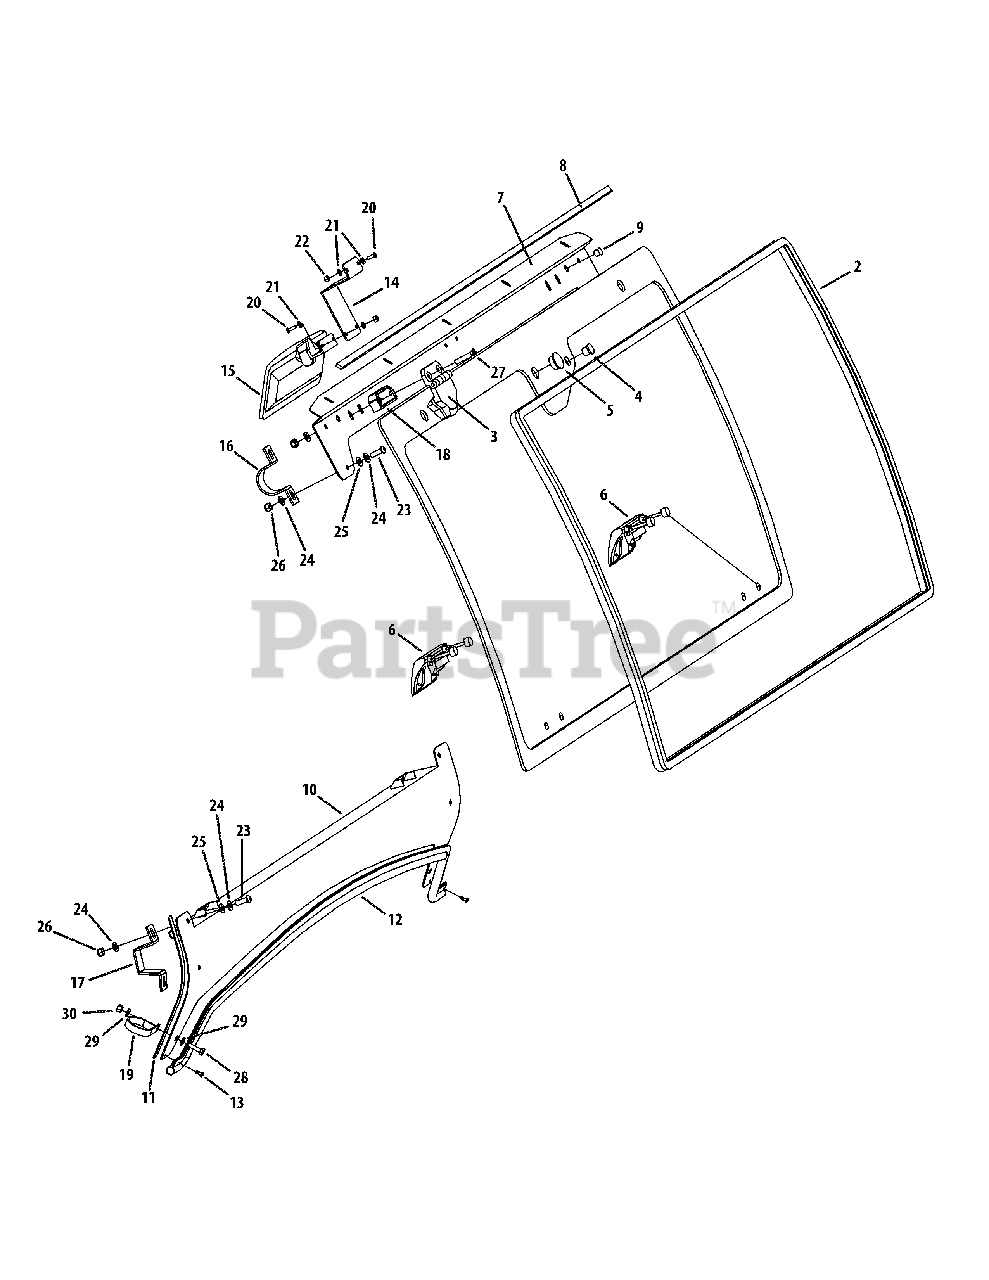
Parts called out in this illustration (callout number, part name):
1	Windshield Assembly, (Ref. 1-6)
2	Windshield Rubber
4	3/4" Hole Plug
5	7/8" Hole Plug
6	Window Latch For Pop-Out
7	Front Roof Mount
8	1/2" V-Groove Weatherseal - 10 Ft.
9	Dome Plug, 7/16", (Bag Of 15)
10	Cowl
11	1/2" V-Groove Weatherseal - 10 Ft.
12	1" Round Bulb Rubber -10 Ft.
14	Rearview Mirror Mount
15	Interior Rear View Mirror
16	Upper Mounting Bracket-Rev C
17	Upper Bracket
18	Pop-Out Windshield Hinge Kit
19	Hardware Kit, P-Clamp
20	Hardware Kit - 10-32 x 5/8" Bolt
21	Hardware Kit - 10-32 Steel Washer
22	Hardware Kit - 10-32 Locknut
23	Hardware Kit - 5/16-18 x 1" Bolt
24	Hardware Kit - 5/16" Steel Washer
25	Hardware Kit - 5/16" Nylon Washer
26	Hardware Kit - 5/16-18 Locknut
27	Hardware Kit - 5/16-18 x 1 3/4 Bolt
28	Hardware Kit - 1/4-20 x 1" Bolt
29	Hardware Kit - 1/4 Steel Washer
30	Hardware Kit - 1/4-20 Locknut
